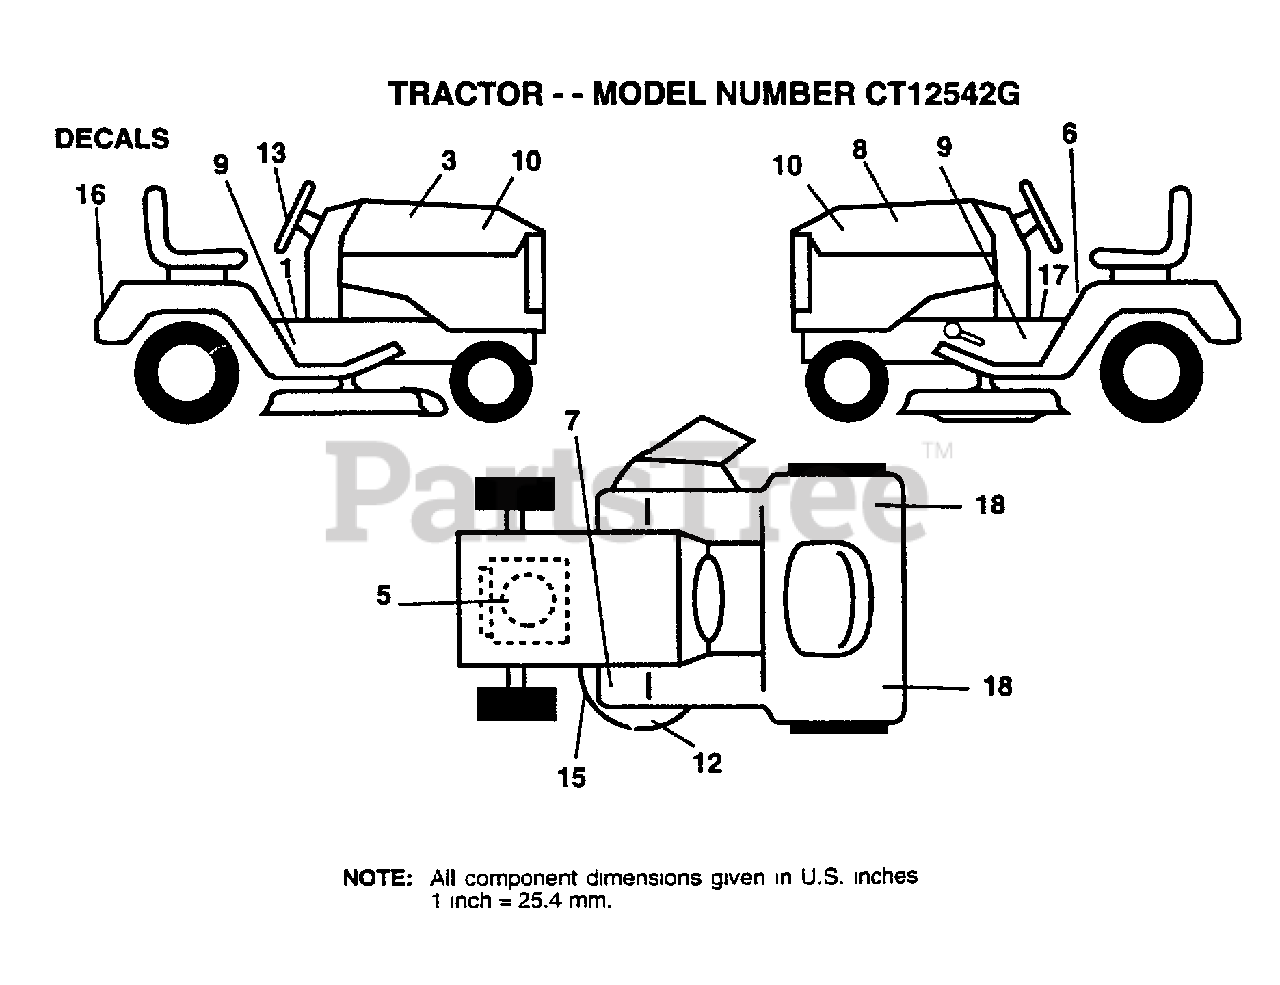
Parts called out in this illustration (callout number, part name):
3	DECAL.HD.RH.RALLY
5	DECAL.ENG.272632
6	DECAL
8	DECAL.HD.LH.RALLY
9	CHASSIS DECAL
10	"DECAL, HP HOOD"
13	DECAL INST STRWHL
15	DECAL
16	DECAL.FENDER
17	DECAL BRAK PARK
18	REFLECTOR-TAIL YT
